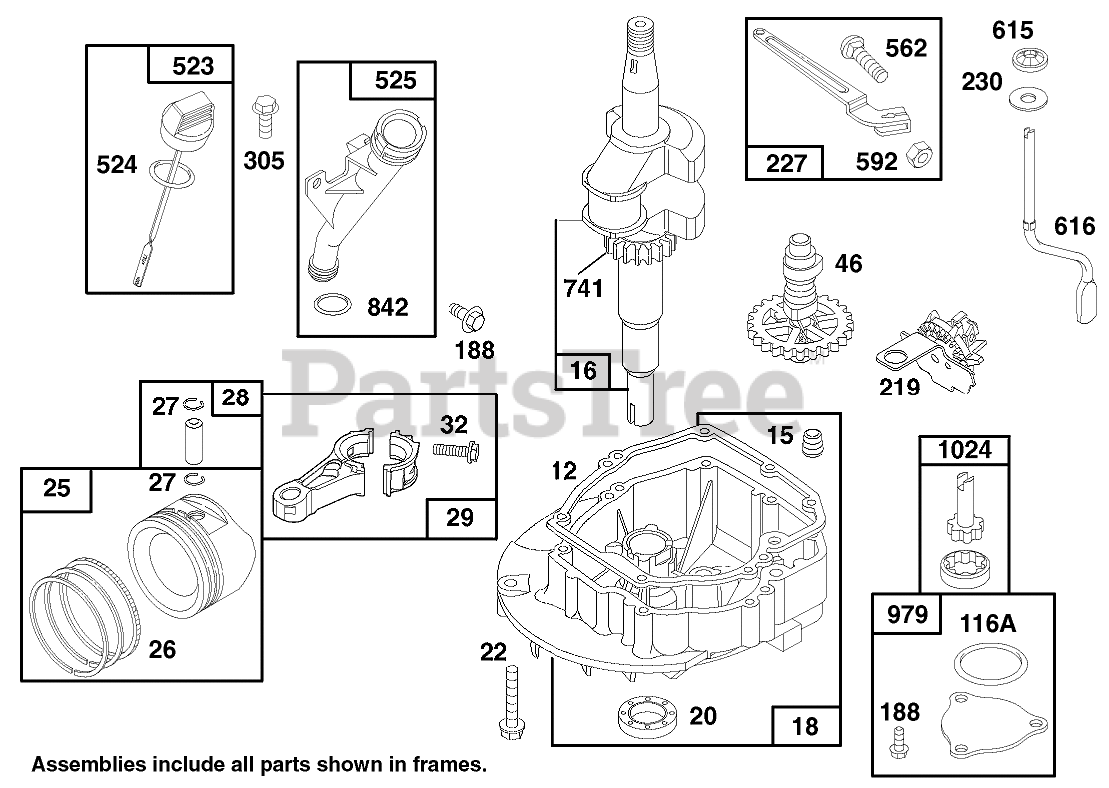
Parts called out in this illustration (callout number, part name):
12	ENGINE BASE GASKET
15	Plug-Pipe
16	CRANKSHAFT
18	ENGINE SUMP
20	SEAL-OIL
22	SCREW - ENGINE BASE
25	STD PISTON ASSEMBLY
26	STD RING SET
27	PISTON PIN LOCK
28	PIN ASM - PISTON
29	STD PISTON ASSEMBLY
32	Connecting Rod
46	CAM GEAR
116A	O RING SEAL
188	SCREW - HEX HEAD
219	GOVERNOR/OIL SLINGER
227	GOVERNOR LEVER ASSEMBLY
230	WASHER
305	SCREW - HEX HEAD
523	DIPSTICK-OIL
524	O-RING
525	OIL FILLER TUBE
562	GOVERNOR LEVER BOLT
592	HEX NUT
615	FASTENER
616	GOVERNOR CRANK
621	STOP SWITCH
741	TIMING GEAR
842	O-RING
979	OIL PUMP COVER
1024	OIL PUMP
